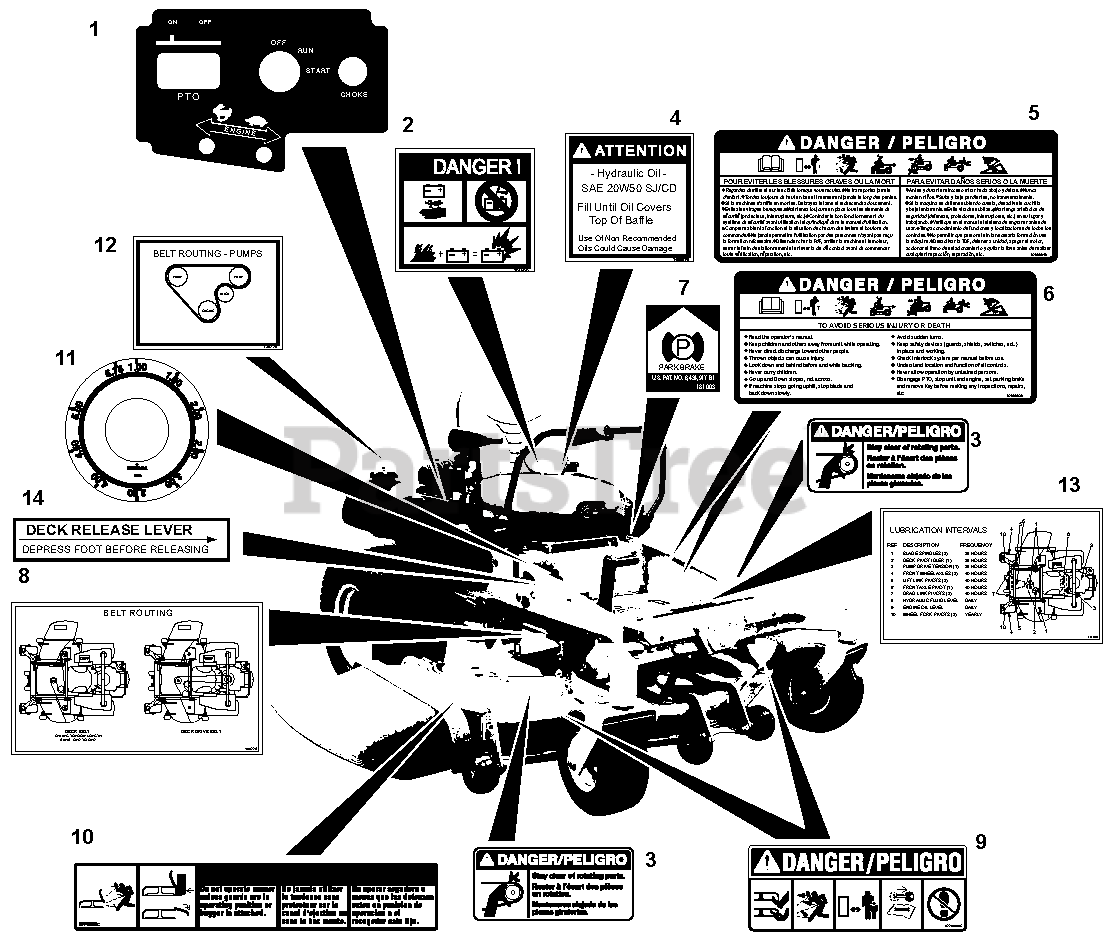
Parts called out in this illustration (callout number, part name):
1	Decal, Control Panel
2	Decal, Danger - Battery
3	Decal, Danger Belt Rotation
4	Attention, Hydraulic Reservoir
5	Decal, Safety French/Spanish
6	Decal, Safety English
7	Decal, Park Brake
8	Decal, Belt Routing
9	Decal, Mower Pan Danger
10	Decal, Warning
11	Decal, HOC Index
12	Decal, Pump Belts
13	Decal, Lubrication Intervals
14	Decal, Deck Release Lever
